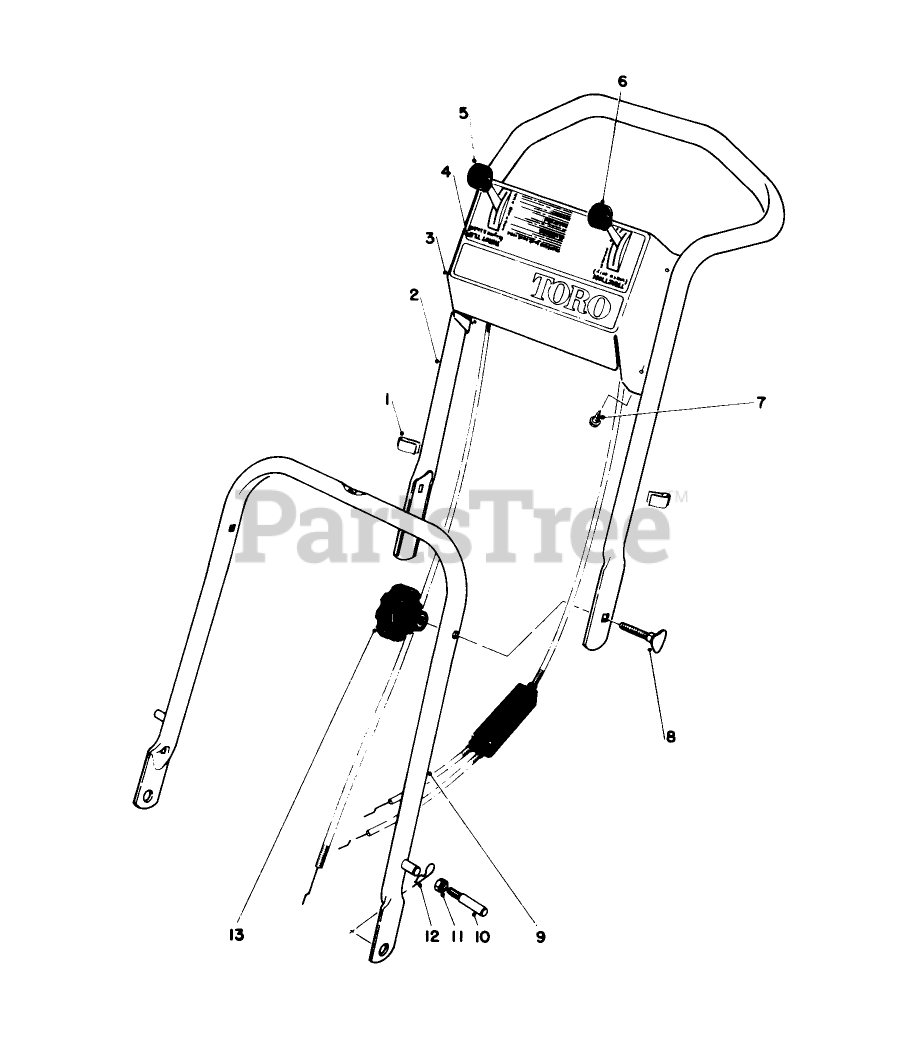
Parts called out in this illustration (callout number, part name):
2	UPPER HANDLE
7	Screw
8	SCREW-HANDLE
10	HANDLE PIN
12	PIN-COTTER, HAIR
